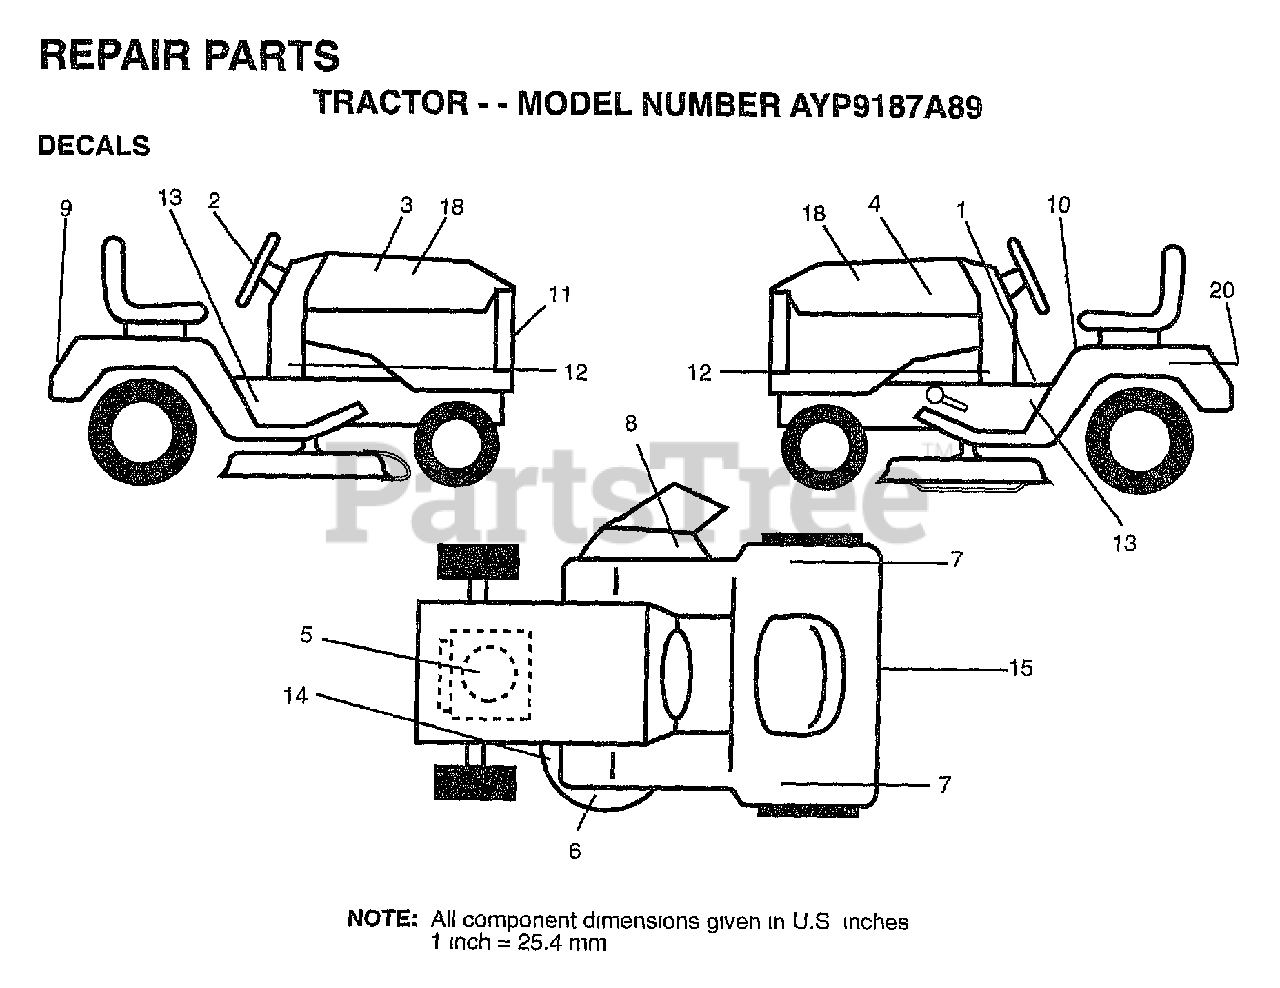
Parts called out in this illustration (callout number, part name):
1	"DEAL-OPER,INST."
2	DECAL STEER WHL
3	DECAL HOOD RH
4	DECAL HOOD LH
5	DECAL, ENGINE
6	DECAL DECK MULCH
7	DECAL.FENDER.AUTO
8	DECAL DECK WIZ +
10	"DECAL DANGER,FEND"
11	DECAL.LENS.WIZARD
12	DECAL PANEL SIDE
13	"DECAL.CHASSIS.42"""
14	"DECAL-SCHEM,BELT"
15	DECAL DRAWBAR LH
18	NAMEPLATE.HD.WIZA
20	DECAL.BATRY.3-3908
